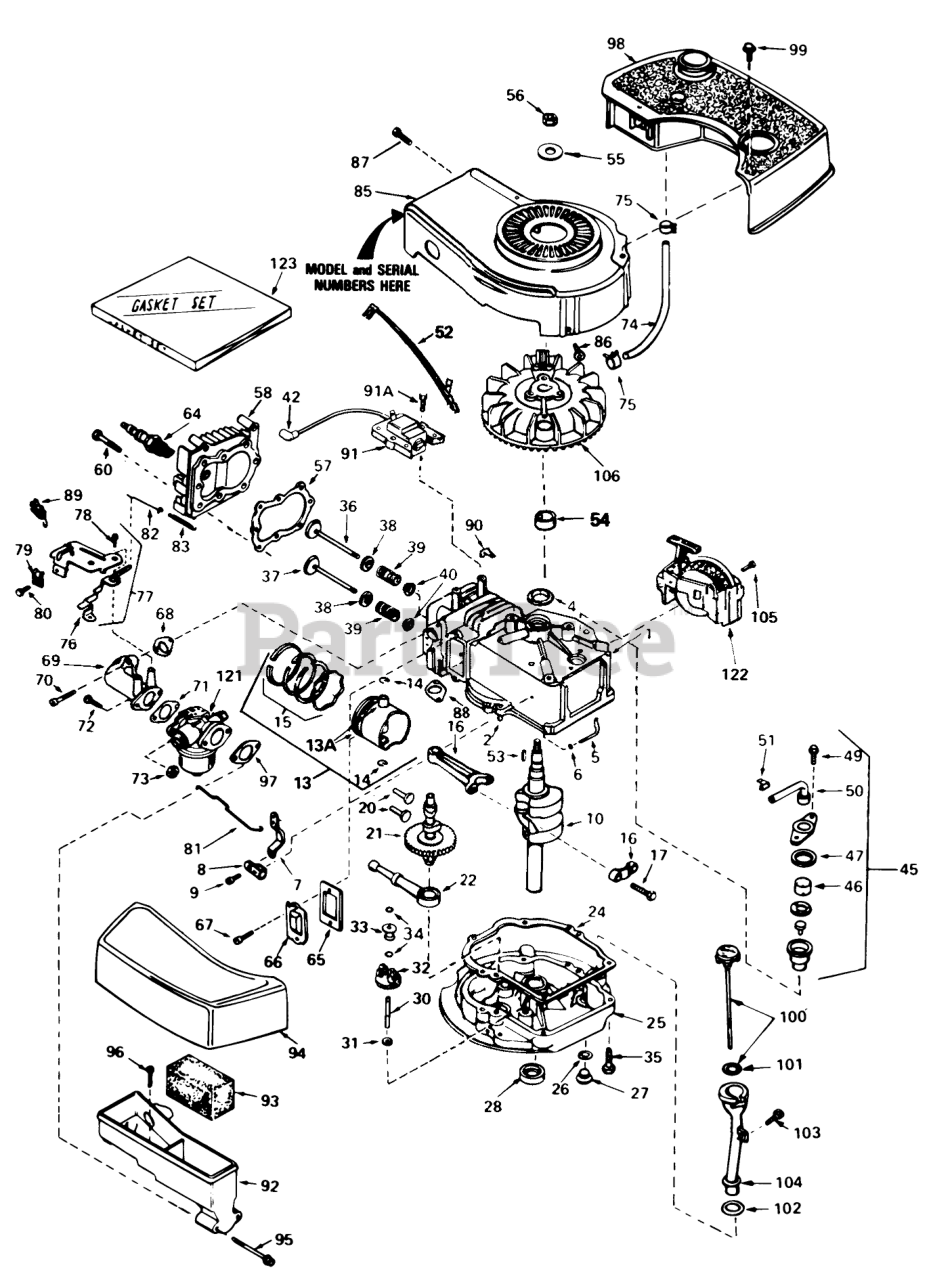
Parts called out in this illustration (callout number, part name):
1	Cylinder Assy. (Incl. #2 & 4)
2	Pin-Dowel
4	Seal-Oil
5	Rod, Governor (Incl. #6)
6	Washer-Flat
7	Governor Lever
8	Clamp-Lever, Governor
9	Screw
10	Crankshaft
13	Piston, Pin & Ring Assy. (Std.)(Incl. #13A, 14 & 15)
13	Piston, Pin & Ring Assy. (.010 oversize)(Incl. #13A, 14 & 15)
13	Piston, Pin & Ring Assy. (.020 oversize)(Incl. #13A, 14 & 15)
13A	Piston & Pin Assy. (Std.)(Incl. #14)
13A	Piston & Pin Assy. (.010 over size)(Incl. #14)
13A	Piston & Pin Assy. (.020 over size)(Incl. #14)
14	Ring-Retaining, Piston Pin
15	Ring Set (Std.)
15	Ring Set (.020" OS)
15	Ring Set (.010" OS)
16	Rod Assy., Connecting (Incl. #17)
17	Bolt-Rod, Connecting
20	Lifter-Valve
21	Camshaft(Mech.Comp. Release)
22	Oil Pump ASM
24	Gasket, Mounting
25	Flange Assy., Mounting (Incl. #26 thru 30)
26	Gasket-Oil Drain
27	Plug Oil Drain
28	Seal Oil
30	Shaft-Governor
31	Washer-Flat
32	Gear Assy., Governor (Incl. #31)
33	Spool-Governor
34	Ring-Retaining
35	Screw (1/4-20 x 1-1/4)
36	Valve, Intake (Std.)(Incl. #40)
36	Valve, Intake (1/32" oversize)(Incl. #40)
37	Valve, Exhaust (Std.)(Incl. #40)
37	Valve, Exhaust (1/32" oversize)(Incl. #40)
38	Cap-Upper Valve Spring
39	Spring-Valve
40	Cap-Valve, Spring
42	Cover-Spark Plug
45	Breather Assy. (Incl. #46 thru 51)
46	Element-Breather
47	Gasket-Breather
49	Screw (10-24 x 9/16)
50	Tube, Breaker
51	Clip, Breather
52	Wire-Ground
53	Key-Flywheel
55	Washer-Belleville
56	Nut-Flywheel
57	63573 GIL 42 SNWTHW
58	Head-Cylinder
60	Screw (5/16-18x1-1/2)
64	Plug, Spark (J17LM or equiv.)
64	Plug, Spark (Champion RCJ-8)
65	Gasket-Breather
66	Cover-Valve
68	Gasket-Intake
69	Pipe, Intake (Incl. #68)
70	Screw (1/4-20 x 1)
71	Gasket-Carburetor
72	Screw (1/4-28 x 7/8)
73	Nut and Lock Washer (1/4-28)
74	Line-Fuel
75	Clamp-Line, Fuel
76	Lever Control
77	Control Assy., Speed (Incl. #76, 78 & 89)
78	Screw, Hex Washer Hd Shoulder Self-Tap
79	Conduit
80	Screw (10-32 x 3/8)
81	Link-Throttle
82	Link Governor Spring
83	Spring Governor
85	Housing-Blower
86	Screw (1/4-20x19/32)
87	Screw (10-24 x 9/16)
88	Gasket Exhaust
89	Terminal
90	Clip-Wire
91	Lamination & Coil Assy. (Solid State)(Incl. #42)
91A	Screw
92	Body Air Cleaner
93	Filer, Air
94	Cove, Air Cleaner
95	Screw Fil Hd.
96	Screw, Hex Hd.
97	Gasket-Air Cleaner
98	Tank-Fuel
99	Screw (10-32 x 35/64)
100	Dipstick, Oil (Incl. #101)
103	Screw (10-32 x 1/2)
104	Tube-Oil Fill
105	Screw (1/2-20x5/8)
106	Flywheel
121	Carburetor (Incl. #71)
122	Starter-Sidemount
123	Gasket Set
